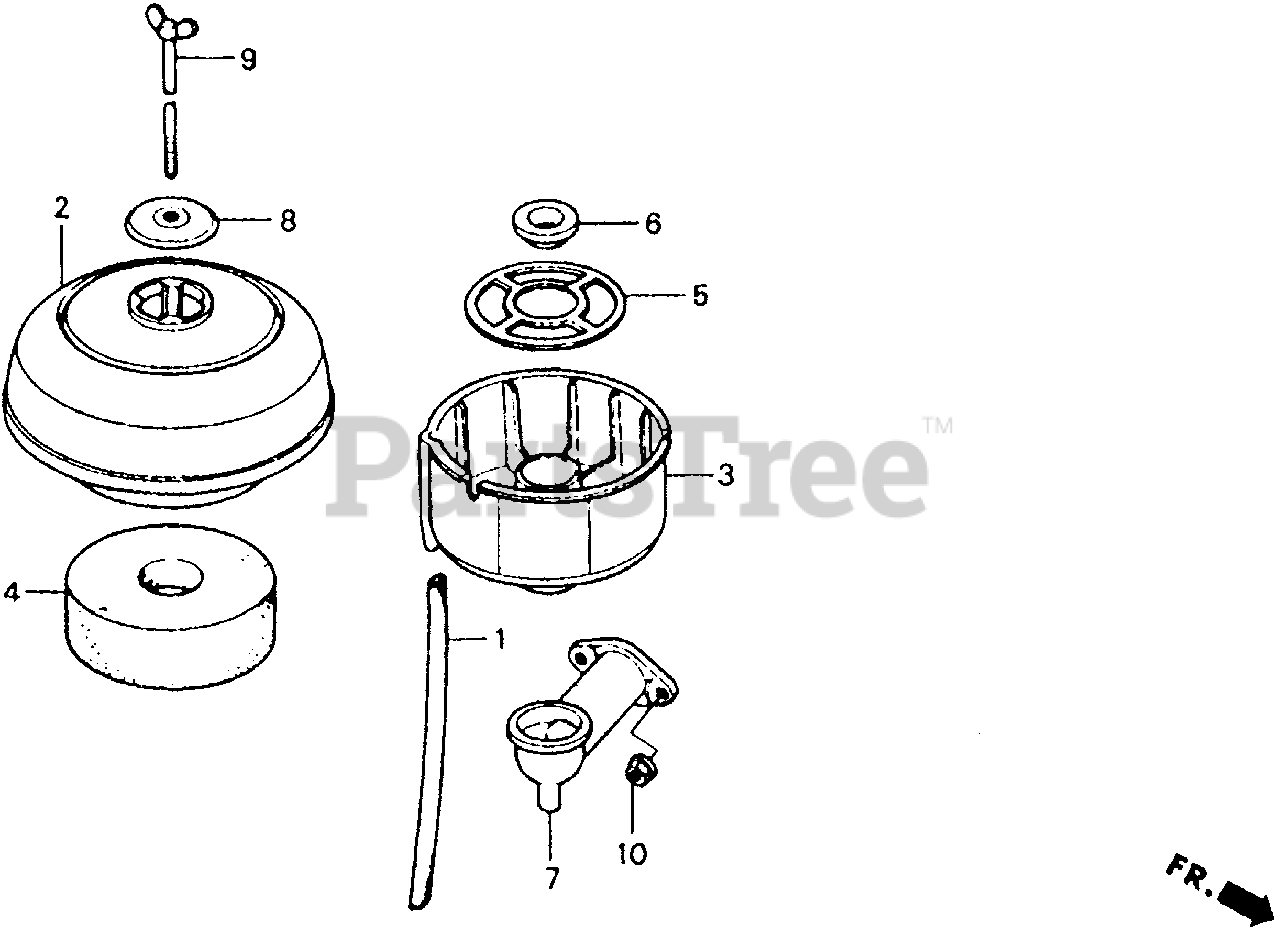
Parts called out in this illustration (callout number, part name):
1	TUBE, BREATHER
2	BODY, CLEANER
3	PAN, AIR CLEANER OIL
4	ELEMENT, AIR CLEANER
5	GRID, AIR CLEANER
6	COLLAR, AIR CLEANER (NOT AVAILABLE)
7	ELBOW, AIR CLEANER
8	CAP, AIR CLEANER
9	BOLT, AIR CLEANER
10	NUT, FLANGE (6MM)
